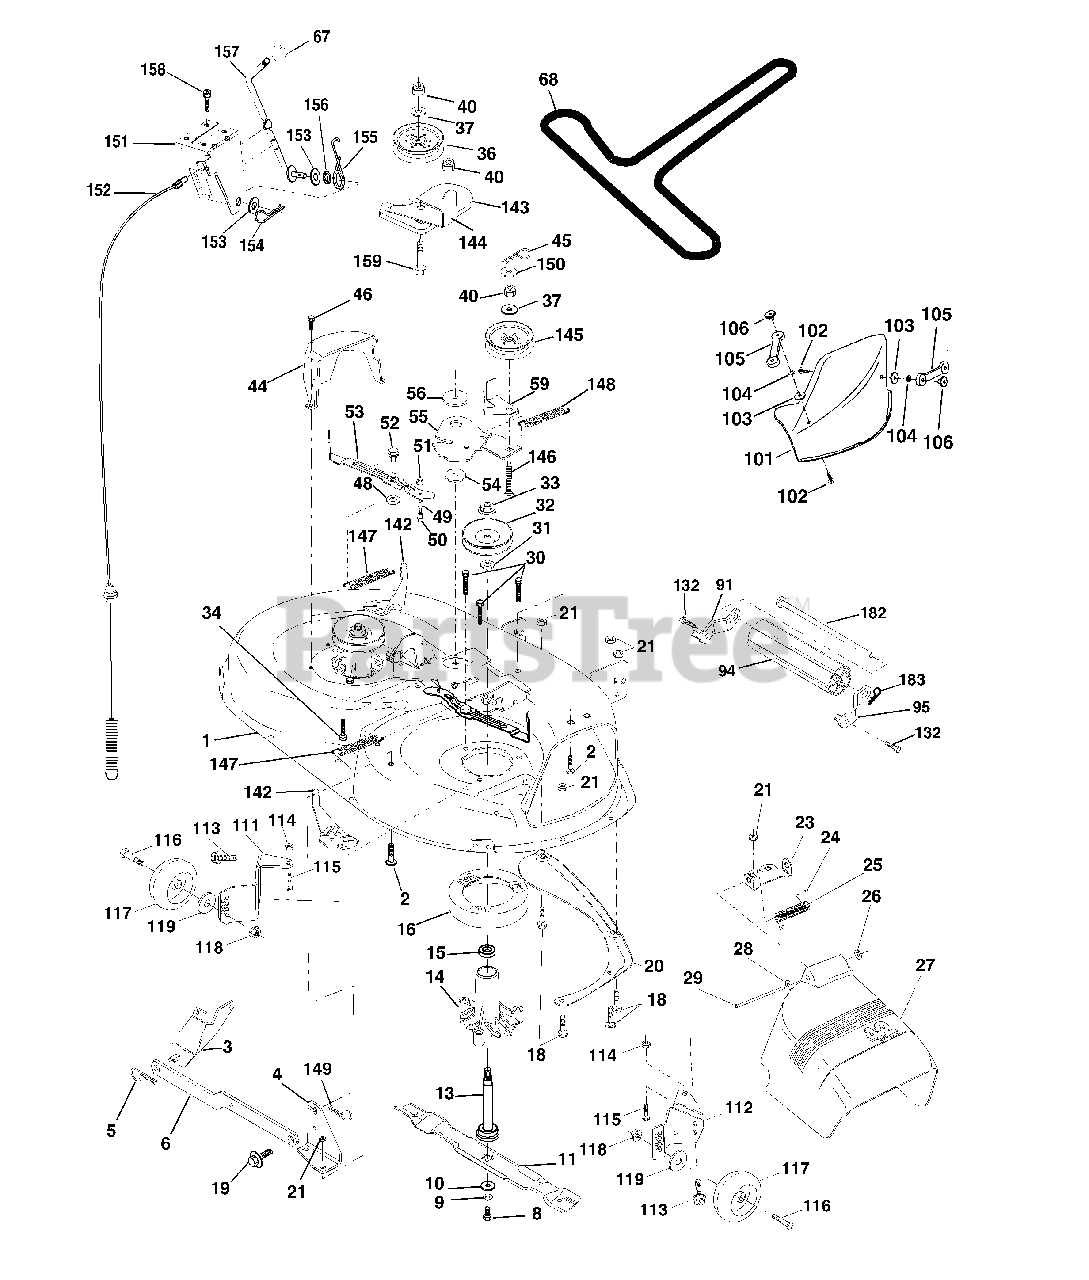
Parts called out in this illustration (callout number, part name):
1	Mower Deck Assembly, 42"
2	Bolt
3	Bracket Asm Fr. Sway Bar 3/42
4	Bracket Asm Deck 42" Sway Bar
5	Retainer Spring
6	Bar Sway Deck
8	Bolt 3/8-24 x 25 Grade 8 patched
9	Washer, Lock
10	Washer, Hardened
11	Blade, Mulching 42"
11	Blade Mower 42" Hi-Lift
13	Shaft Assembly, Mandrel, Vented
14	Housing, Mandrel, Vented
15	Bearing, Ball, Mandrel
16	Stripper, Mandrel Deck
18	Bolt, Carriage 5/16-18 x 5/8
19	Bolt, Shoulder
20	Baffle, Vortex
21	Nut
23	Bracket, Deflector Mower 42"
24	Cap, Sleeve 80 x 112 Blk Mower
25	Spring, Torsion, Deflector 2 52
26	Nut, Push Phos & Oil
27	Shield, Deflector 42" Blk
28	Washer 11/32 x 5/8 x 16 Gauge
29	Rod, Hinge 42" 6 75 W/G
30	Screw Thdrol Washer Head
31	Washer, Spacer Mower Vented
32	Pulley, Mandrel
33	Nut, Toplock 9/16 Flange
34	Bolt
36	Pulley, Idler, Flat
37	Washer 13/32 x 13/16 x 16 Gauge
40	Nut
44	Guard, Mandrel, LH
45	Retainer
46	Screw, Thdrol 1/4-20 x 5/8 T
48	Washer, Hardened
49	Roller Assembly, Cam Follower
50	Bolt, Shoulder #10-24 Grade 5
51	Locknut
52	Bolt, Shoulder 5/16-18 UNC
53	Arm Assembly, Pad, Brake
54	Washer, Hardened
55	Arm, Idler
56	Spacer, Retainer
59	Guard TUV Idler
67	Knob
68	V-Belt, 42" Mower
91	Bracket Asm. Noseroller LH
94	Roller, Nose
95	Bracket Asm. Noseroller RH
101	Mulcher Cover
102	Screw
103	Washer, Flat
104	Washer, Lock
105	Latch Assembly
106	Nut, Weld
111	Bracket, Gauge, Wheel LH
112	Bracket, Gauge, Wheel RH
113	Screw 3/8-16 x .625
114	Nut, Keps 5/16 - 18 UNC
115	Bolt, Carriage 5/16-18 x 5/8
116	Bolt, Shoulder
117	Wheel, Gauge
118	Nut Centerlock 3/8-16
119	Washer 3/8 x 7/8 x 14 Ga.
132	Screw 3/8-16 x .75
142	Arm Spring Brake Mower
143	Bracket Arm Idler 42"
144	Keeper Belt 42" Clutch Cable
145	Pulley Idler Flat
146	Bolt Carriage Idler
147	Spring Extension
148	Spring Return Idler
149	Retainer Spring Yellow
150	Washer 9/32 x 3/4 x 16 Ga.
151	Bracket Clutch Cable
152	Clutch Cable 42"
153	Washer Flat 3/8" Type B
154	Spring Retainer
155	Spring Retention LVR CLTCH CAB
156	Spacer Clutch Cable
157	Rod Clutch Cable 3/8"
158	Screw Hex Thd Cut 1/4-20 x 1/2
159	Bolt Rdhd Sqn 3/8-16 UNC x 1-3/4
182	Rod Roller Nose
183	Retainer Spring
